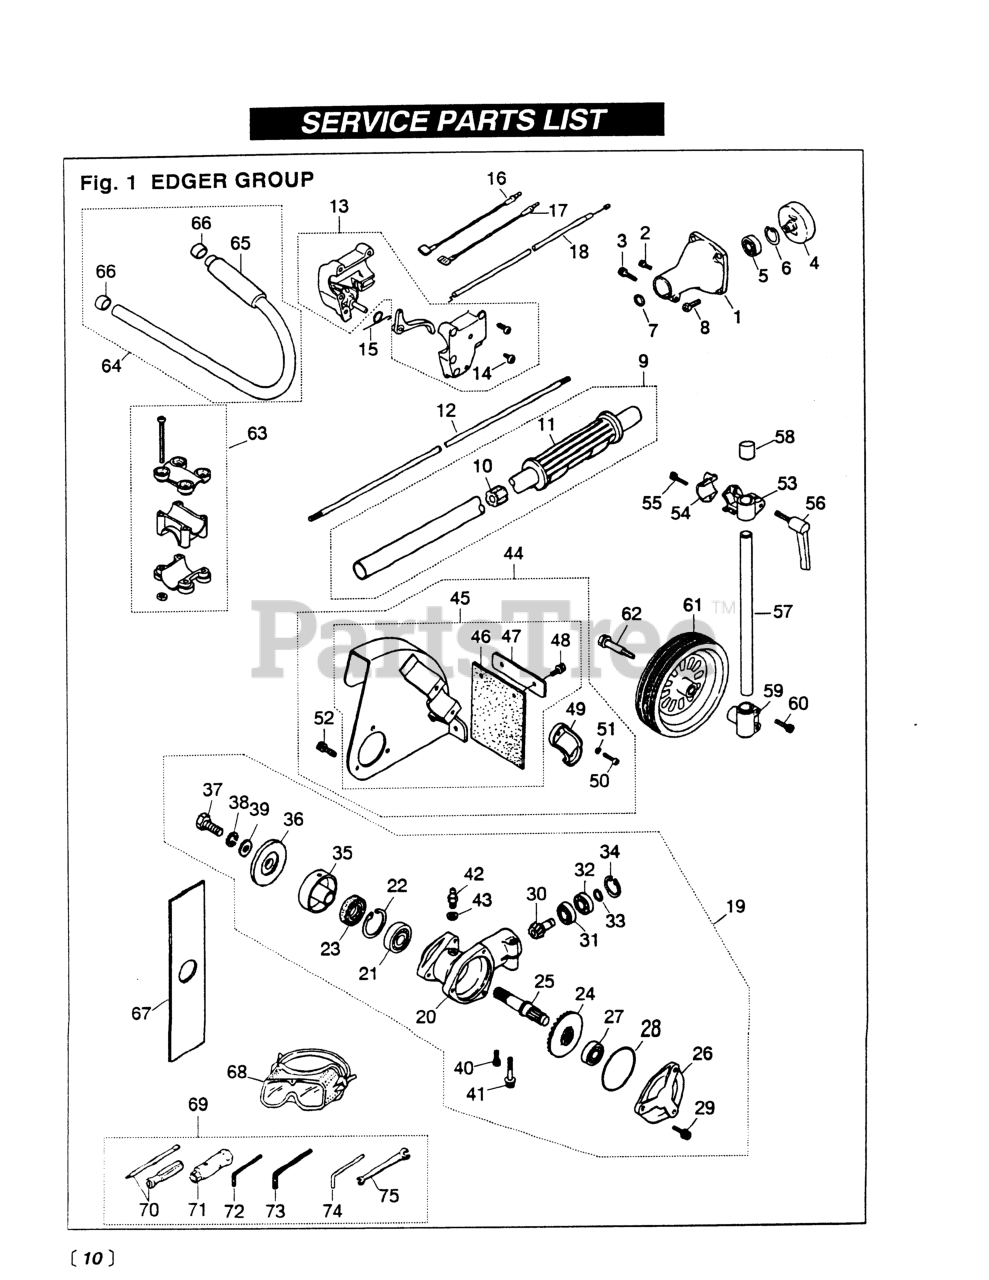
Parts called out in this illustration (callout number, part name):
2	BOLT, M5 X 10
3	BOLT, M5 X 25
4	DRUM CLUTCH (USE 6460-12112)
5	BEARING
6	RING, SNAP, M28 x 1.2
8	BOLT, M6 X 20
10	SPACER, DRIVE SHAFT
14	SET SCREW, ANTI-ROTATION
15	SPRING, THROTTLE TRIGGER
16	CORD, RED (LEAD WIRE)
17	CORD, BLACK (LEAD WIRE)
19	GEARCASE ASSEMBLY
20	GEARCASE
22	RING, SNAP, M32 x 1.2
23	SEAL, OIL
24	GEAR
25	SHAFT, GEAR
26	COVER
27	BEARING (RPLS T3403-13510)
28	O-RING
29	BOLT
30	PINION
31	BEARING (RPLS T3403-13530)
32	BEARING (RPLS T3300-13531)
33	RING, SNAP (RPLS T3300-13330)
35	HOLDER (A)
36	HOLDER (B)
37	BOLT, LH
38	WASHER (RPLS 3180-13270)
39	WASHER, M8 x 2.3 (RPLS -20823)
40	BOLT, M5 X 10
41	BOLT, M6 x 1.35
42	FITTING, GREASE
43	WASHER, M6 X .8
46	PLATE (RUBBER)
47	PLATE (REPLACES -24130)
48	BOLT, M5 X 12
49	CLAMP
50	BOLT, M6 X 18
51	WASHER, M6 X 15
52	BOLT
53	BRACKET (NLA)
55	BOLT, M5 X 22
56	LEVER
57	TUBE, EDGER
58	CAP
59	BRACKET (NO LONGER AVAILABLE)
60	BOLT, M6 X 25
61	WHEEL, EDGER
62	BOLT
63	HANDLE BRACKET ASSEMBLY
64	J-HANDLE ASSEMBLY
65	GRIP, HANDLE
66	CAP
68	GOGGLE
69	TOOL SET
70	SCREWDRIVER
72	WRENCH (TOOL)
73	WRENCH (TOOL)
74	BAR
75	SPANNER, 8 X 10 (RPLS 2540- )
